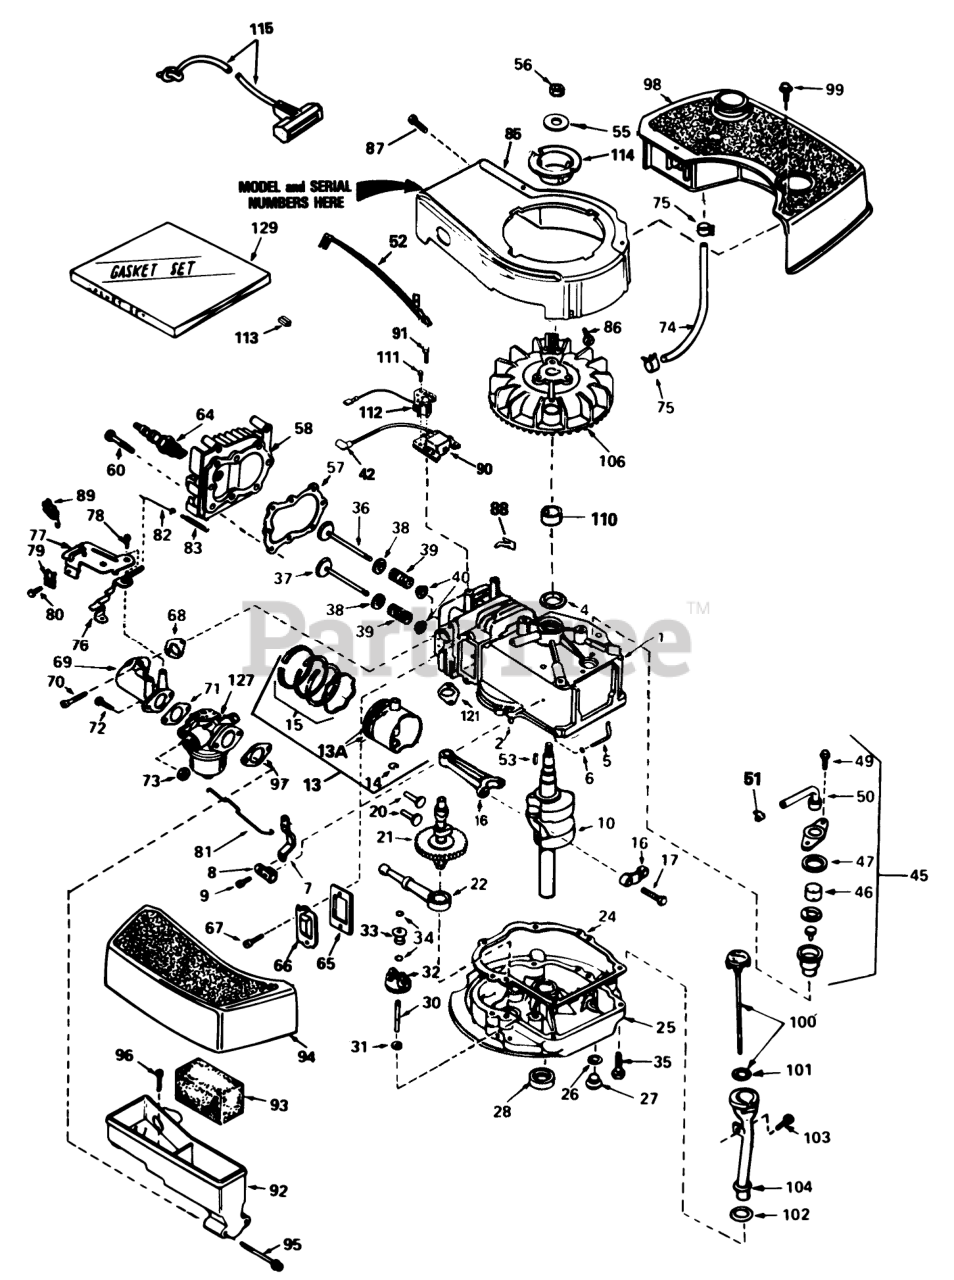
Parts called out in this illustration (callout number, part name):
1	Cylinder Assy. (Incl. Ref. #2 & 4)
2	Pin-Dowel
4	Seal-Oil
5	Rod, Governor (Incl. Ref. #6)
6	Washer-Flat
7	Governor Lever
8	Clamp-Lever, Governor
9	Screw
10	Crankshaft
13	Piston, Pin & Ring Assy. (Std.)(Incl. Ref. #13A, 14 & 15)
13	Piston, Pin & Ring Assy. (.010 Oversize)(Incl. Ref. #13A, & 15)
13	Piston, Pin & Ring Assy. (.020 Oversize)(Incl. Ref. #13A, & 15)
13A	Piston & Pin Assy. (Std.)(Incl. Ref. #14)
13A	Piston & Pin Assy. (.010 Oversize)(Incl. Ref. #14)
13A	Piston & Pin Assy. (.020 Oversize)(Incl. Ref. #14)
14	Ring-Retaining, Piston Pin
15	Ring Set (Std.)
15	Ring Set (.020" OS)
15	Ring Set (.010" OS)
16	Rod Assy., Connecting (Incl Ref. #17)
17	Bolt-Rod, Connecting
20	Lifter-Valve
21	Camshaft(Mech.Comp. Release)
22	Oil Pump ASM
24	Gasket
25	Flange Assy., Mounting (Incl. Ref. #26, 27, 28 & 30)
26	Gasket-Oil Drain
27	Plug Oil Drain
28	Seal Oil
30	Shaft-Governor
31	Washer-Flat
32	Gear Assy., Governor (Incl. Ref. #31)
33	Spool-Governor
34	Ring-Retaining
35	Screw (1/4-20 x 1-1/4)
36	Valve, Intake (Std.)(Incl. Ref. #40)
36	Valve, Intake (1/32" Oversize)(Incl. Ref. #40)
37	Valve, Exhaust (Std.)(Incl. Ref. #40)
37	Valve, Exhaust (1/32" Oversize)(Incl. Ref. #40)
38	Cap-Upper Valve Spring
39	Spring-Valve
40	Cap-Valve, Spring
42	Cover-Spark Plug
45	Breather Assy. (Incl. Ref. #46 thru 51)
46	Element-Breather
47	Gasket-Breather
49	Screw (10-24 x 9/16)
50	Tube, Breaker
51	Clip, Breather
52	Wire-Ground
53	Key-Flywheel
55	Washer-Belleville
56	Nut-Flywheel
57	63573 GIL 42 SNWTHW
58	Head-Cylinder
60	Screw (5/16-18x1-1/2)
64	Plug, Spark (J17LM or equiv.)
64	Plug, Spark (Champion RCJ-8)
65	Gasket-Breather
66	Cover-Valve
68	Gasket-Intake
69	Pipe, Intake (Incl. Ref. #68)
70	Screw (1/4-20 x 1)
71	Gasket-Carburetor
72	Screw (1/4-28 x 7/8)
73	Nut and Lock Washer (1/4-28)
74	Line-Fuel
75	Clamp-Line, Fuel
76	Lever Control
77	Control Assy., Speed (Incl. Ref. #76, 78 & 79)
78	Screw, Hex Washer Hd Shoulder Self-Tap
79	Conduit
80	Screw (10-32 x 3/8)
81	Link-Throttle
82	Link Governor Spring
83	Spring Governor
85	Housing Blower
86	Screw (1/4-20x19/32)
87	Screw (10-24 x 9/16)
88	Clip-Wire
89	Terminal
90	Solid State
91	Screw
92	Body Air Cleaner
93	Filer, Air
94	Cove, Air Cleaner
95	Screw Fil Hd.
96	Screw, Hex Washer Hd Shoulder Self-Tap
97	Gasket-Air Cleaner
98	Tank-Fuel
99	Screw (10-32 x 35/64)
100	Dipstick, Oil (Incl. Ref. #101)
103	Screw (10-32 x 1/2)
104	Tube-Oil Fill
106	Flywheel
111	Screw (8-32x27/64)
112	Coil, Alternator
113	Terminal
114	Hub-Starter
115	Rope Assy., Starter
121	Gasket Exhaust
127	Carburetor (Incl. Ref. #71)
129	Gasket Set
